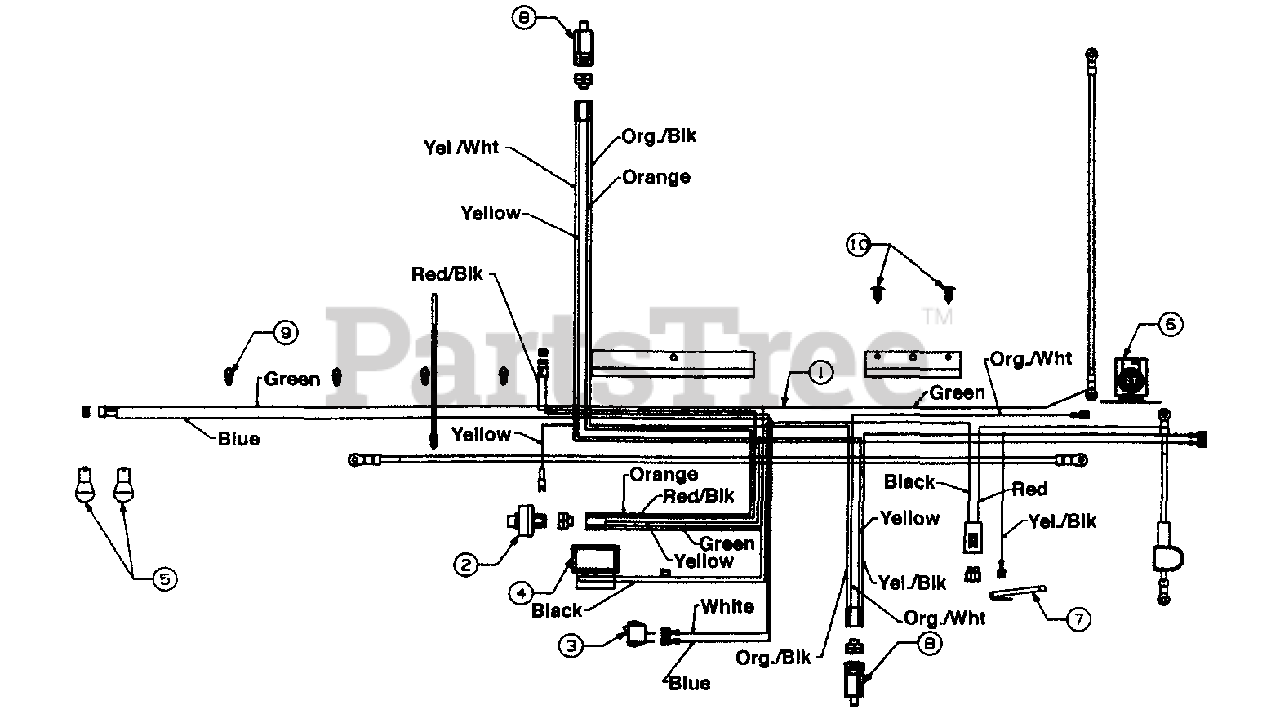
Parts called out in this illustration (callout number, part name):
1	Wire Harness w/Light Switch and Amp
2	Ignition Switch
3	Light Switch
4	Ammeter
5	Bulb (Headlight)
6	Solenoid
7	Safety Switch (Reverse)
8	Safety Switch
9	Wire Retainer Clip
10	Ratchet
